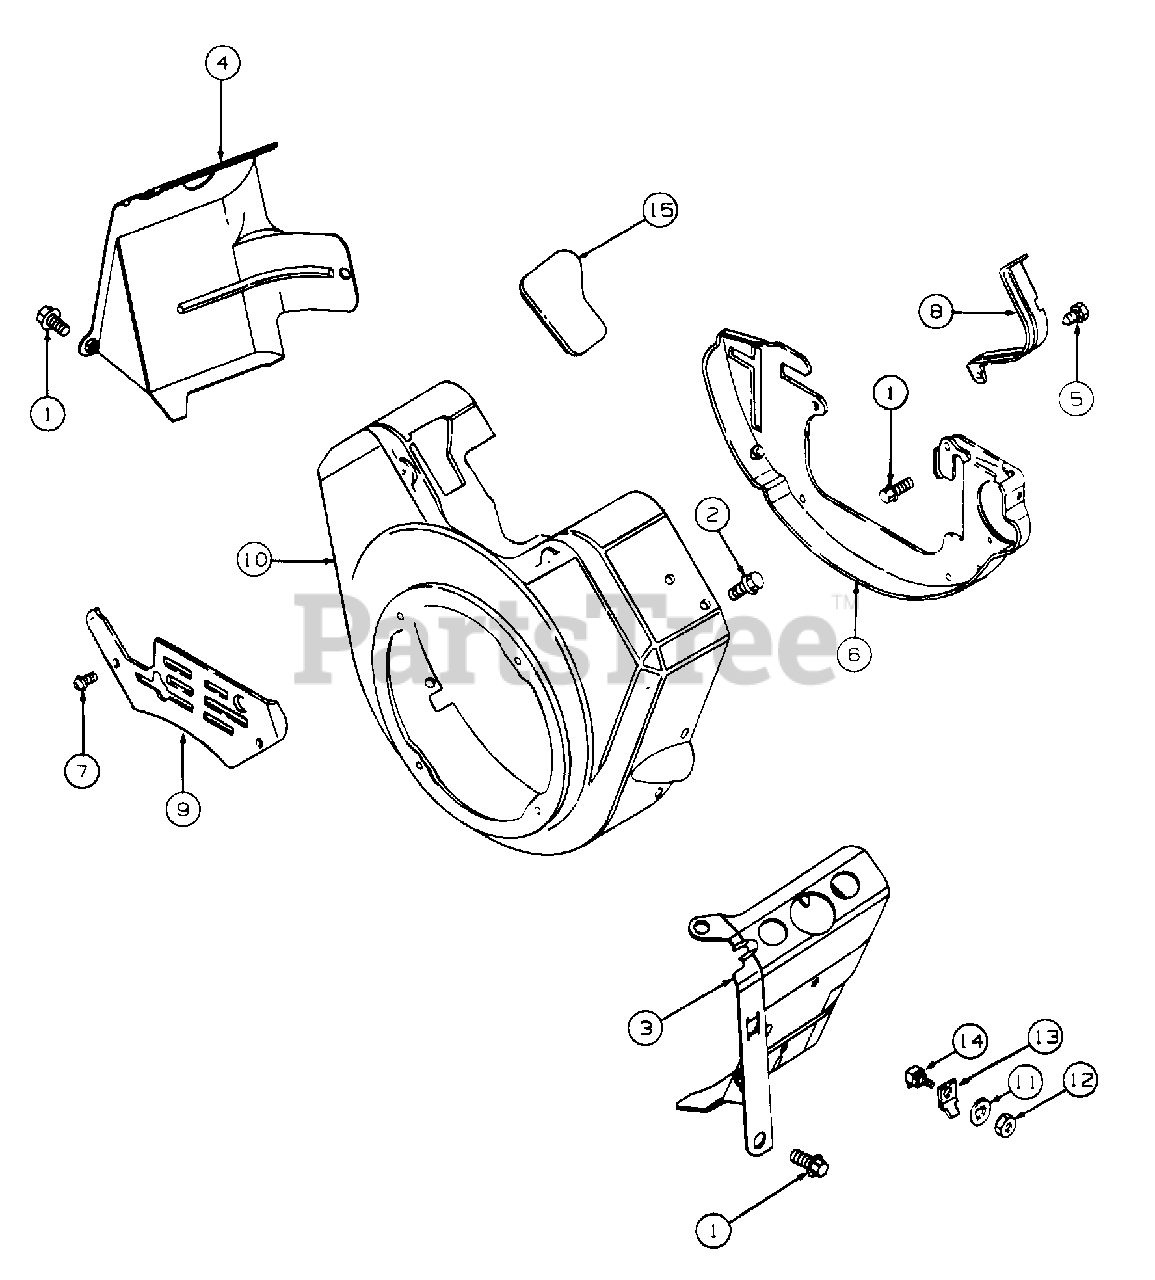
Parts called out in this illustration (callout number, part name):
1	Screw, Sems
2	Screw, Sems
3	Cover (Cylinder #1)
4	Cover (Cylinder #2)
5	Screw, Sems
6	Plate, Back
7	Screw, Sems
9	Cover, Carburetor
10	Housing, Blower
11	Washer, Lock, Internal Tooth
13	Terminal, Ground
14	Insulator Assy
15	Plug, Blower Housing
